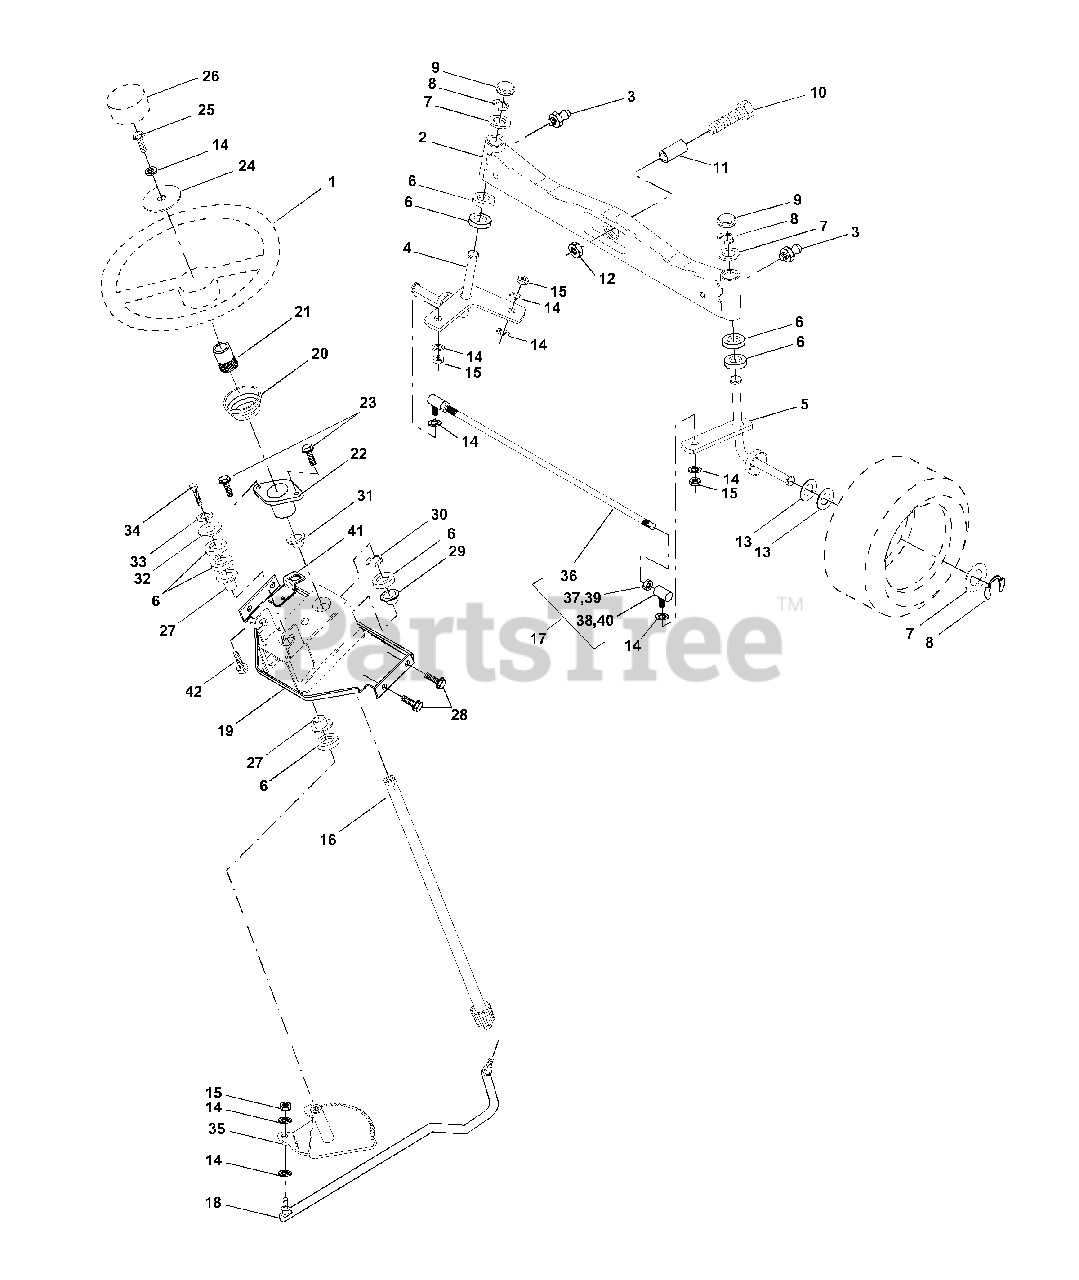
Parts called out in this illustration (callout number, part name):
1	Wheel, Steering
2	Axle Asm., Front
3	Fitting, Grease
4	Spindle Asm, LH
5	Spindle Asm., RH
6	Bearing, Race Thrust Harden
7	Washer 25/32 x 1-5/8 x 16 Ga.
8	Ring, Klip #T5304-75
9	Cap, Spindle
10	Bolt, Fin Hex 5/8-11 x 2-3/4
11	Spacer Brg Axle Front 1.570
12	Nut, Lock Flange 5/8-11 Unc
13	Washer 25/32 x 1-1/4 x 16 Ga.
14	Washer, Lock Hvy Hlcl Spr 3/8
15	Nut Lock Center 3/8-24 Unf
16	Shaft Asm., Steering
17	Rod Asm., Tie Ball J Ball Vgt
18	Draglink, Ball Joint Solid Vgt
19	Support Asm., Steering Vgt
21	Adapter, Wheel Steering
22	Bushing, Strg.
23	Screw
24	Washer 13/32 x 1-1/20 x 11 Ga.
25	Bolt, Fin Hex 3/8-16 x 1 Gr. 5
26	Cap , Wheel Steering
27	Bearing, Col. Strg.
28	Screw 3/8-16 x 3/4
29	Bearing, Flange
30	Ring, Klip Truarc #5304-75
31	Bushing, Nyliner Snap
32	Washer 11/32 x 1 x 10 Ga.
33	Washer, Lock Hvy Hlcl Spr 5/16
34	Bolt, Hex Hd 5/16-18 x 3/4
35	Gear, Sector Steering
36	Tie Rod
37	Jam Nut RH Thread
38	Joint Asm. Ball RH Thread
39	Jam Nut LH Thread
40	Joint Asm. Ball LH Thread
41	Bracket Switch Inerlock VGT97
42	Screw 5/16-18 x 1/2
